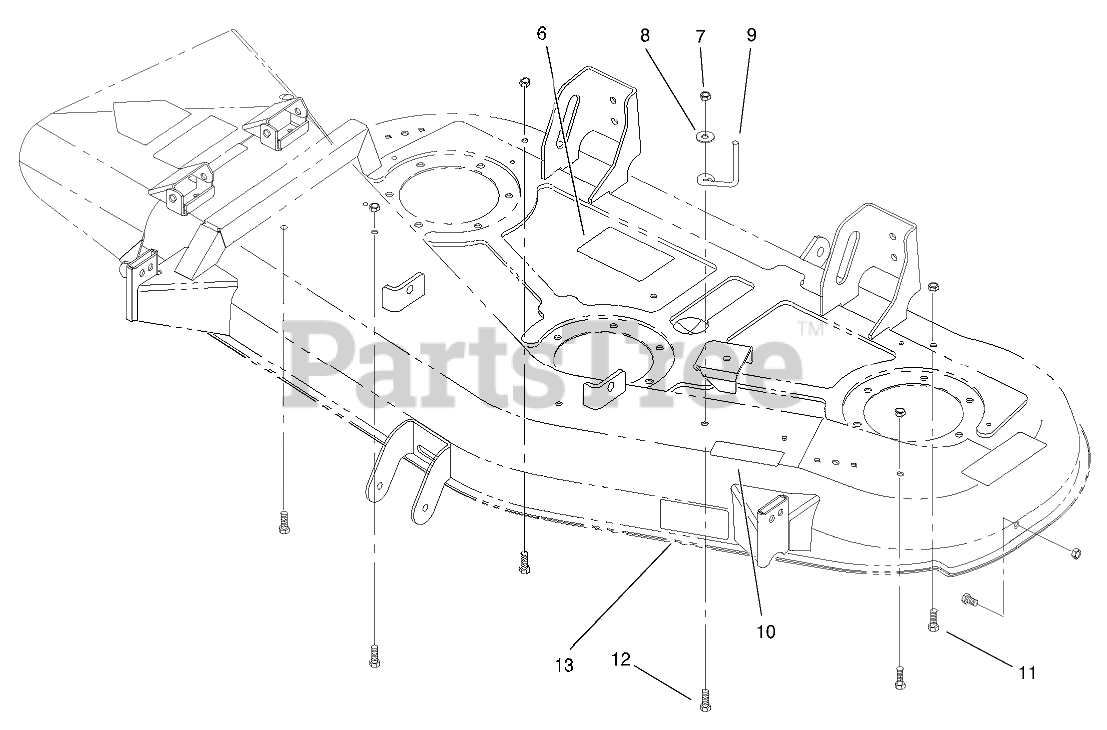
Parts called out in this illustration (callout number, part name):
6	DECAL-BELT ROUTING
7	NUT-LOCK, NI
8	WASHER-PLAIN
9	GUIDE-BELT
10	DECAL-BELT ROUTING
11	SCREW-HH
12	SCREW-HH
13	DECAL-ADJUSTMENT, WHEEL
